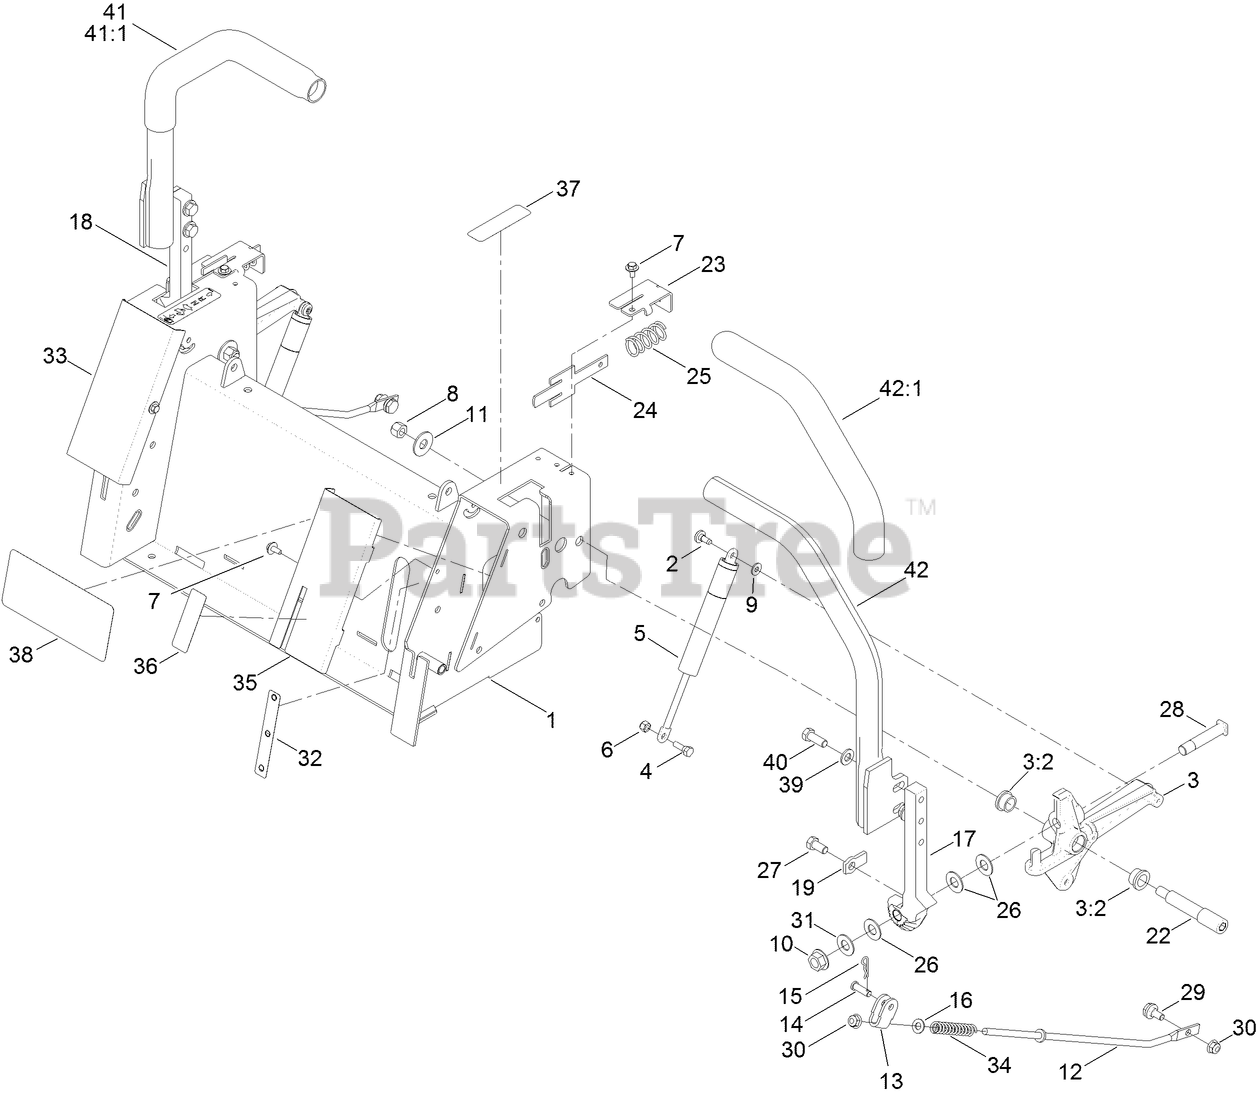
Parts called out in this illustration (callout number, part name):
1	BOX-CONTROL
2	SCREW-SHOULDER
3	ACTIVATOR ARM ASM
3:2	BUSHING
4	BOLT-SHOULDER
5	DAMPER-CONTROL, MOTION
6	NUT-LOCK, NI
7	SCREW-HHFTF
8	NUT-LOCK, NI
9	WASHER
10	NUT-HF
11	WASHER-FLAT
12	ROD-CONTROL
13	BRACKET-CONTROL
14	PIN-CLEVIS
15	PIN-COTTER
16	WASHER-PLAIN
17	ARM-ACTUATOR, LH
18	ARM-ACTUATOR, RH
19	TAB-STOP
22	BOLT-SHOULDER
23	BRACKET-RETURN
24	PLATE-RETURN
25	SPRING-COMPRESSION
26	WASHER-PIVOT
27	SCREW-HH
28	BOLT-SHOULDER
29	BOLT-SHOULDER,HFH
30	NUT-HF, NI
31	WASHER-TEFLON
32	DECAL-FILL, FUEL
33	COVER-CONTROL, RH
34	SPRING-RETURN, NEUTRAL
35	COVER-CONTROL, LH
36	DECAL-BRAKE, PARKING
37	DECAL-CONTROL, MOTION
39	WASHER-FLAT
40	SCREW-HH
41	RH LEVER/GRIP ASM
41:1	GRIP-CONTROL, MOTION
42	LH LEVER/GRIP ASM
42:1	GRIP-CONTROL, MOTION
